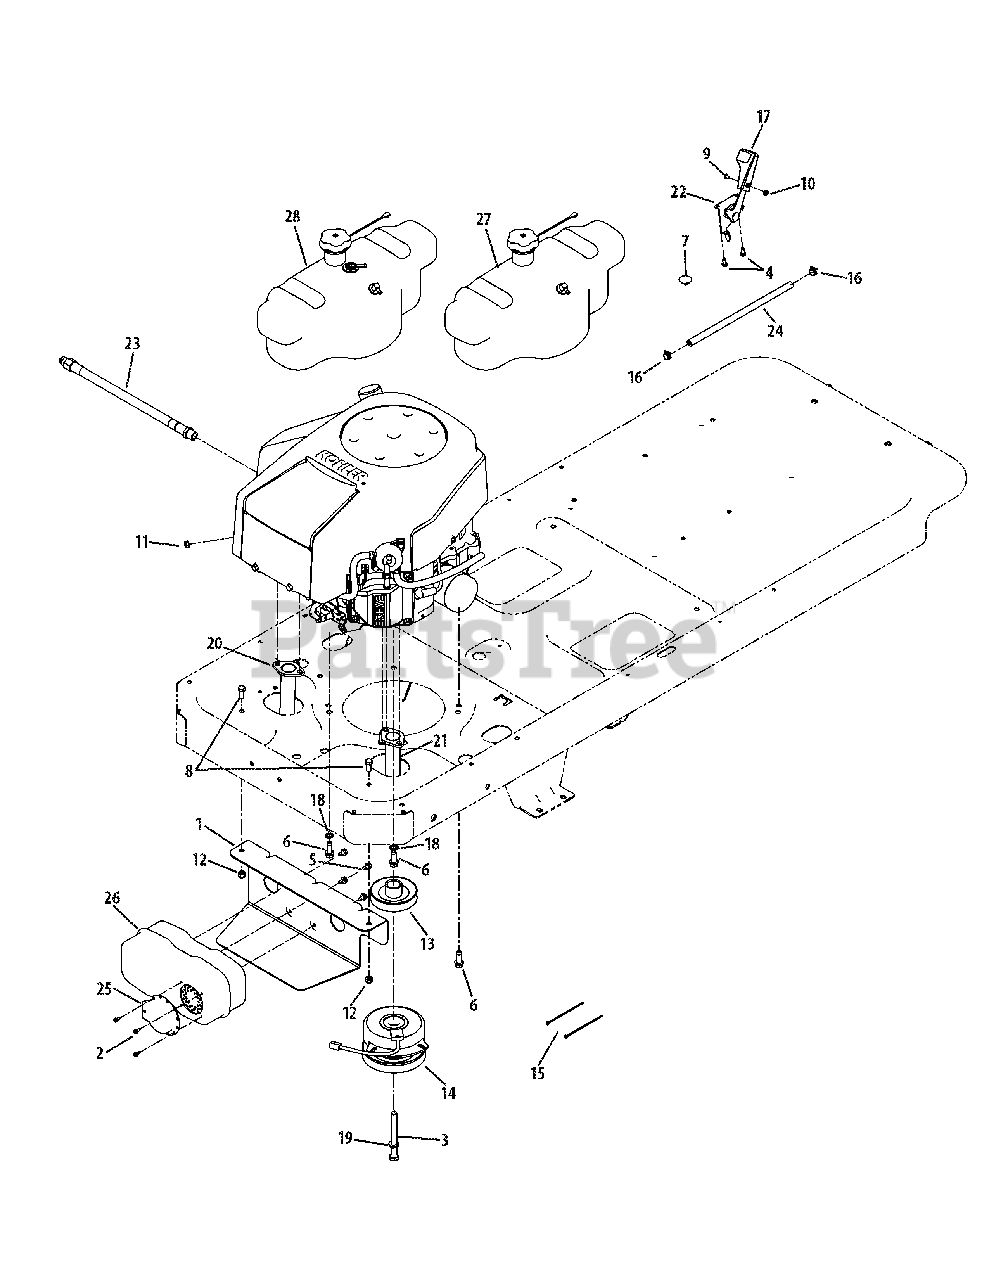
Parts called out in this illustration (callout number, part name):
1	Muffler Mounting Bracket
2	Hex Washer Screw, #8-18 x .5
3	Hex Screw, 7.16-20 x 3.50
4	Hex Washer Screw, #12-16 x .5
5	Hex Washer Screw, 1.4-20 x .5
6	Hex Washer Screw, 3.8-16 x 1.0
7	Choke Plug
8	Hex Screw, 5.16-18 x .75
9	Machine Screw, #8-32 x .375
10	Hex Nut, #8-32
11	Hex Nut, 1.4-20
12	Hex Lock Nut, 5.16-18
13	Drive Pulley
14	Electric PTO Clutch
15	Clutch Wire Tie
16	Hose Clamp
17	Throttle Control Knob
18	Lock Washer, 3.8
19	Lock Washer, 7.16
20	Exhaust Pipe, LH
21	Exhaust Pipe, RH
22	Throttle/choke Cable Assembly
23	Oil Drain Extension Hose
24	Fuel Line Hose
25	Muffler Deflector
26	Muffler
27	Fuel Tank Assembly
27	Fuel Tank Bushing
27	Fuel Pick-Up Fitting
27	Fuel Tank
27	Fuel Cap
28	Fuel Tank Assembly
28	Fuel Tank Bushing
28	Rubber Grommet
28	Rollover Valve Grommet
28	Fuel Pick-Up Fitting
28	Fuel Cap
